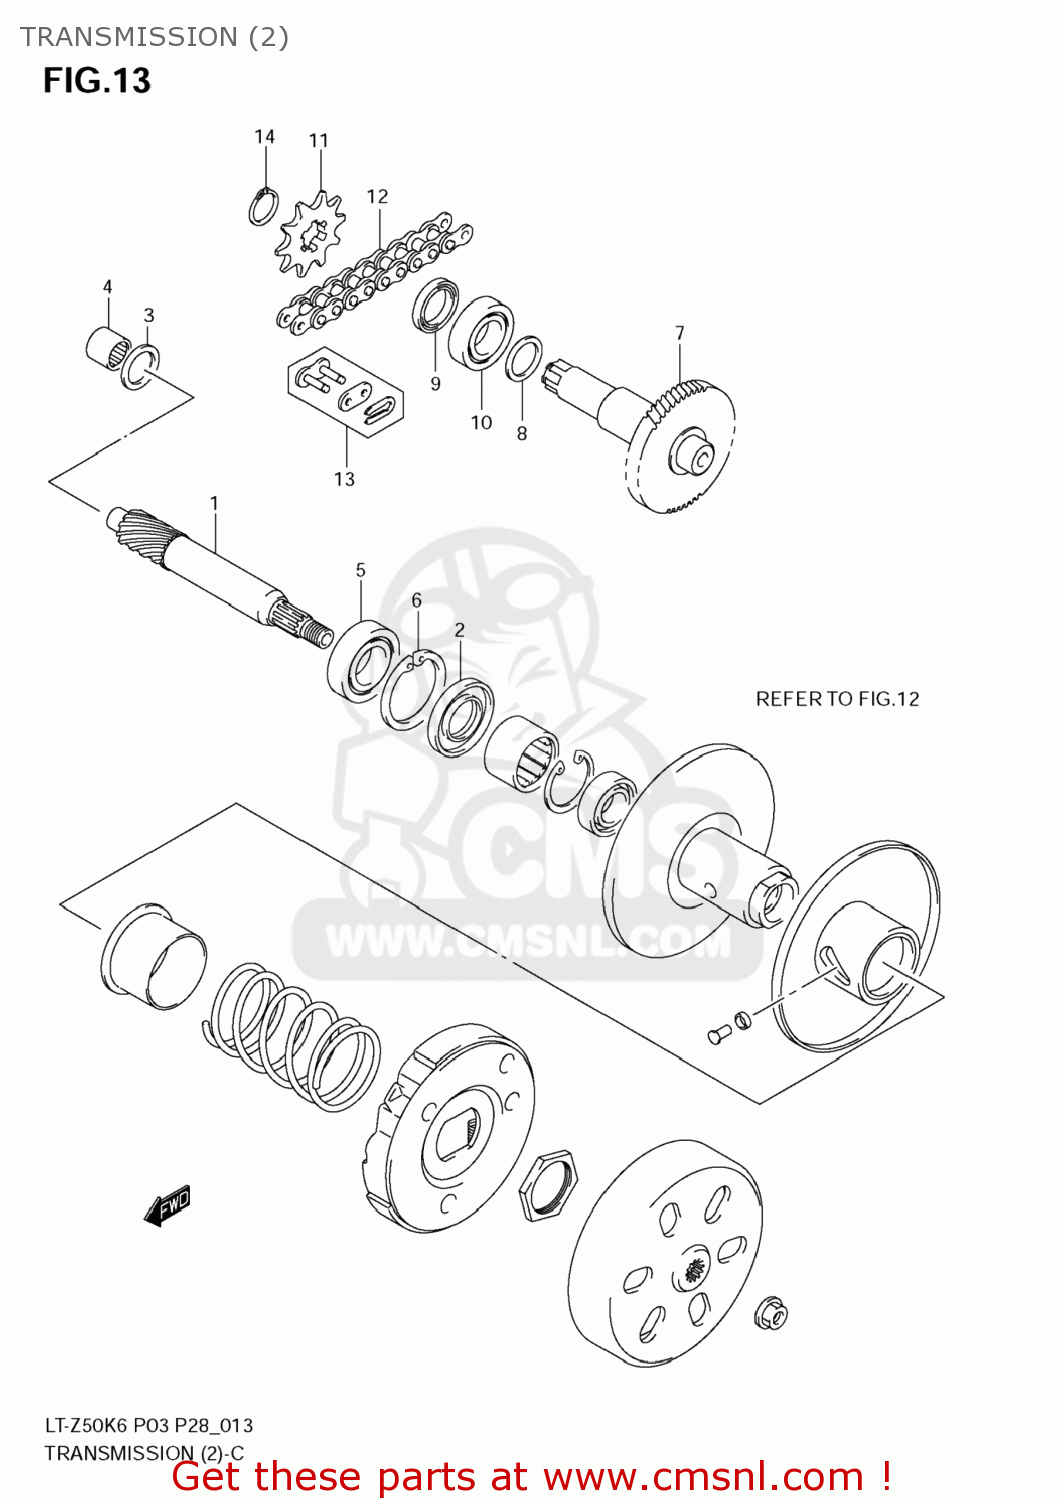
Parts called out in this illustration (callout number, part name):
1	SHAFT,COUNTER
2	SEAL,OIL(17X40X5)
3	SHIM(13X22X0.5)
4	BEARING(12X16X10)
5	BEARING
6	CIRCLIP
7	SHAFT,DRIVE
8	SHIM(17X24X1)
9	SEAL,OIL(17X27X6)
10	BEARING
11	SPROCKET,ENGINE
12	CHAIN,DRIVE
13	JOINT SET,CHAIN
14	CIRCLIP 16MM
